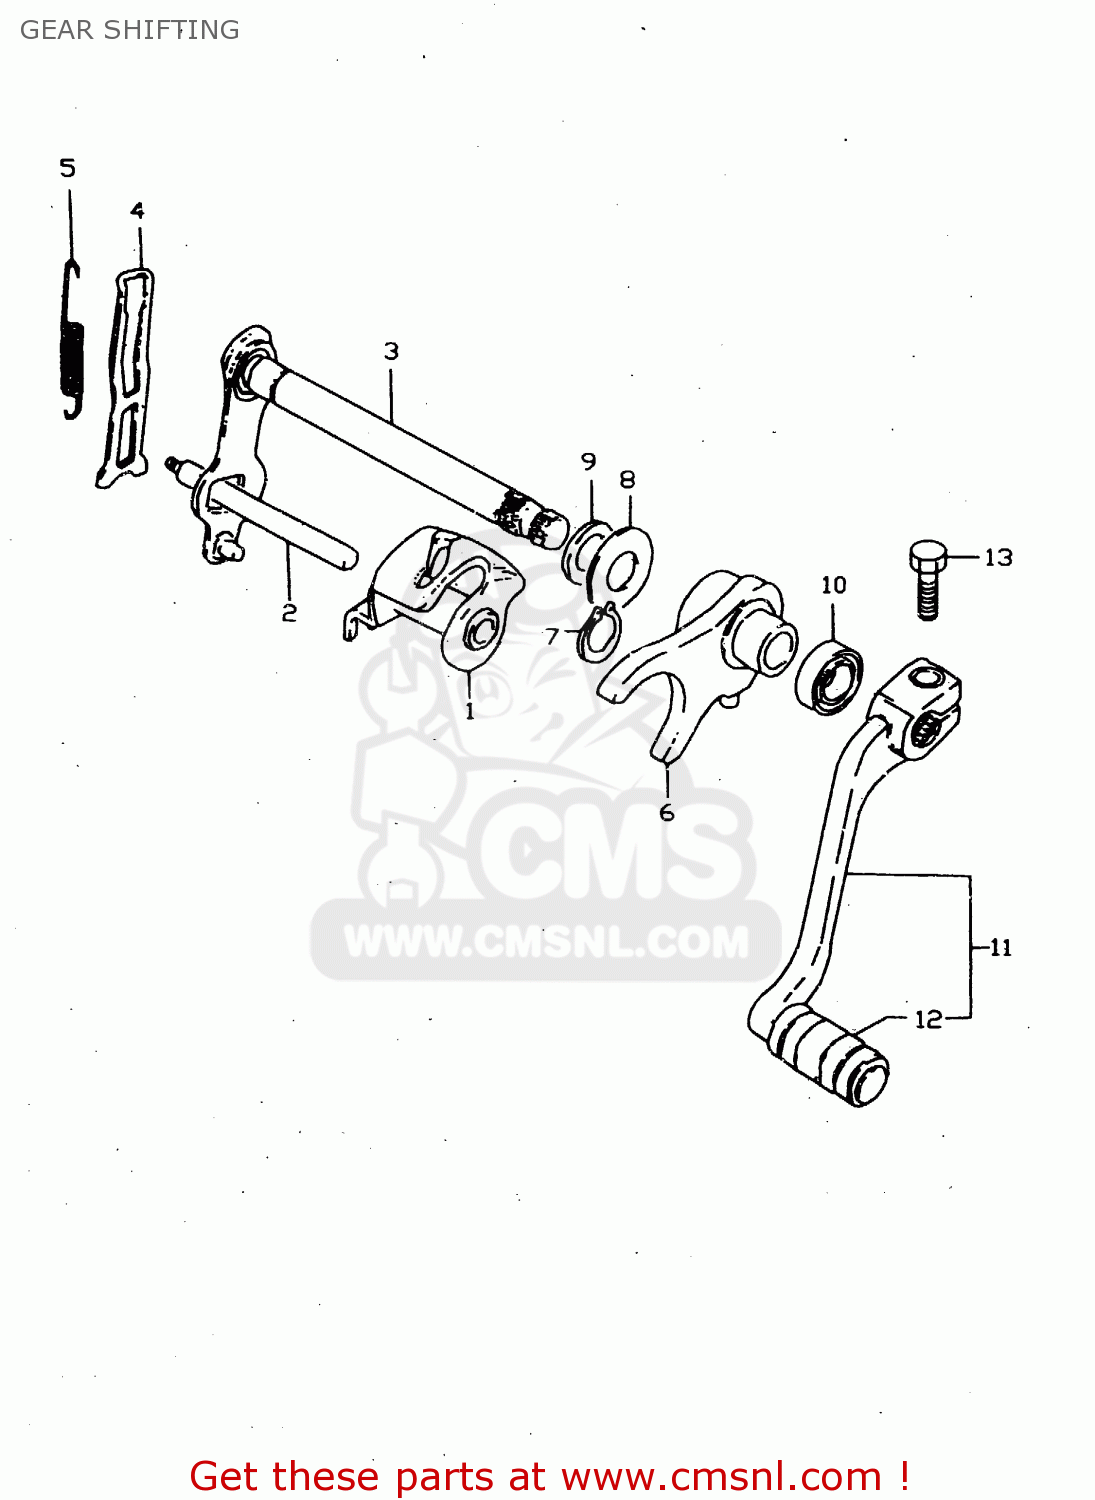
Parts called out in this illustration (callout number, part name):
1	CAM,GEAR SHIFT
2	SHAFT,GEAR SHIFT CAM
3	SHAFT,GEAR SHIFT
4	ARM,GEAR SHIFT CAM STOPPER
5	SPRING
6	FORK,GEAR SHIFT NO.1
7	CIRCLIP,12 MM
8	WASHER
9	WASHER
10	OIL SEAL
11	LEVER ASSY,GEAR SHIFT
12	RUBBER,GEAR SHIFT PEDAL
13	BOLT
